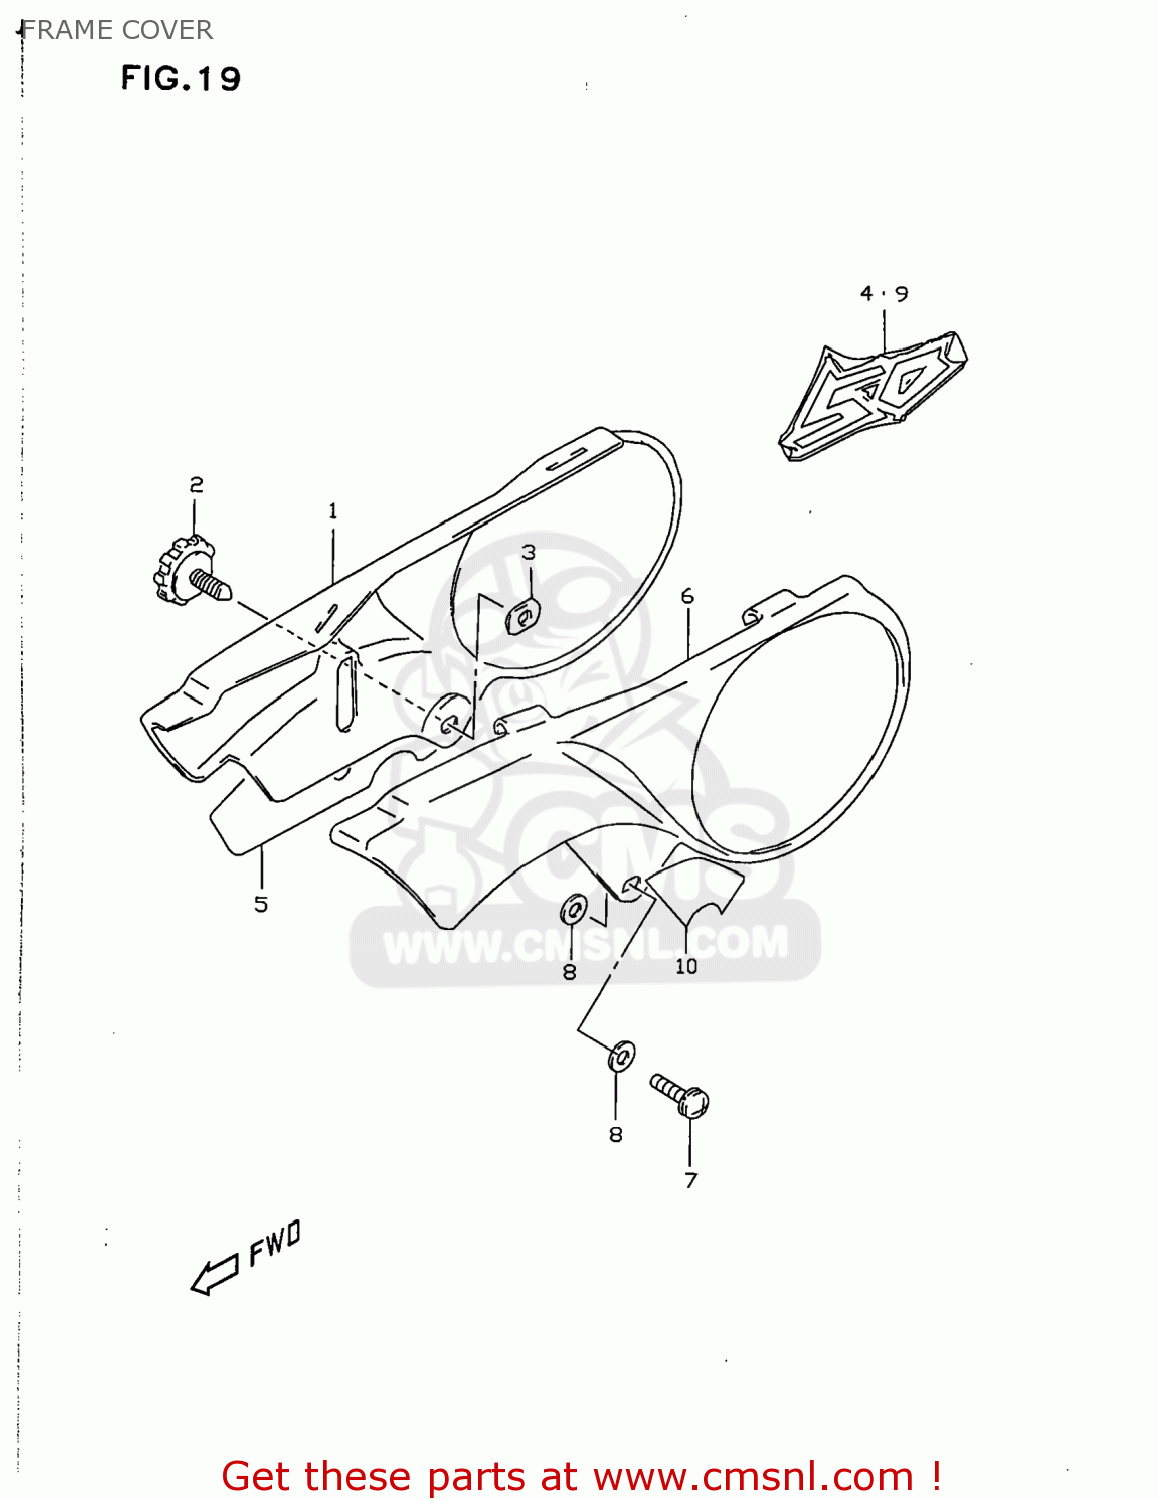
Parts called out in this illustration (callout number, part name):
1	COVER,FRAME,R(WHITE)
2	KNOB,FRAME COVER,R
3	NUT
4	EMBLEM,FRAME COVER
5	EMBLEM,FRAME COVER,R LWR
6	COVER,FRAME,L(WHITE)
7	SCREW
8	WASHER(6.5X18X1.6)
9	EMBLEM,FRAME COVER
10	EMBLEM,FRAME COVER,L LWR
